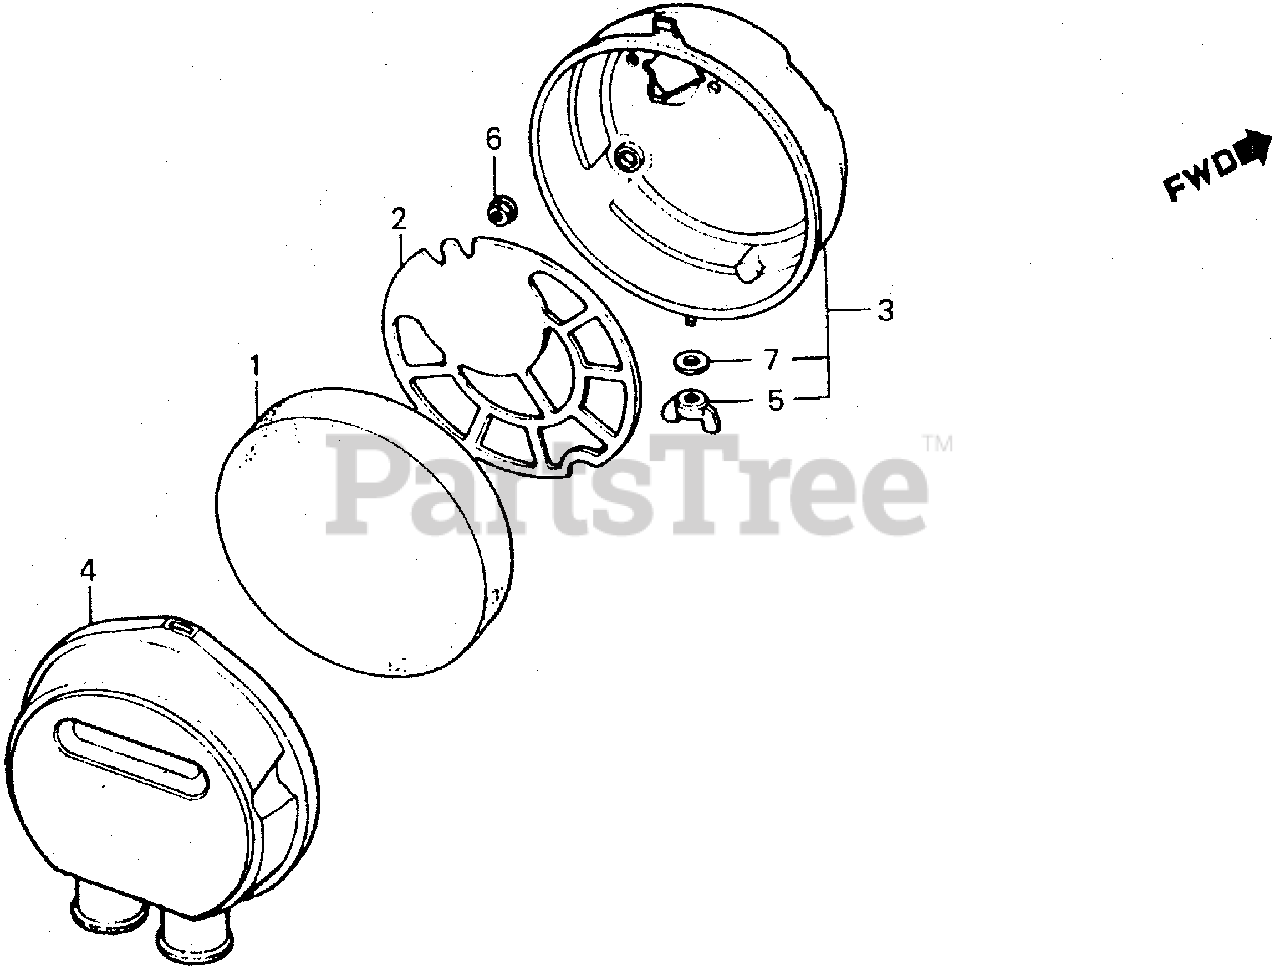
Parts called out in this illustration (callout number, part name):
1	ELEMENT, AIR CLEANER
2	GRID, AIR CLEANER
3	HOUSING, AIR CLEANER
4	COVER, AIR CLEANER
5	WINGNUT, TOOL BOX SETTING
6	NUT, FLANGE (6MM)
7	WASHER, PLAIN (6MM)
